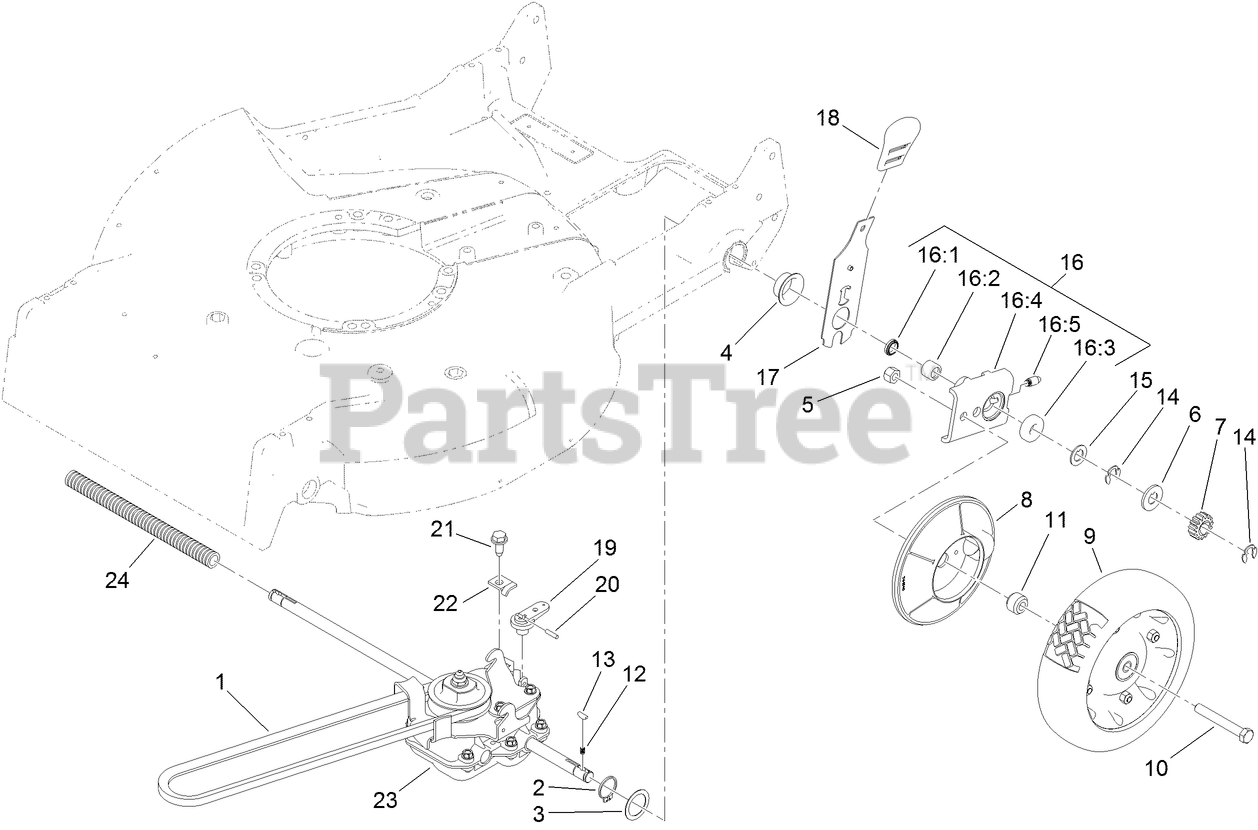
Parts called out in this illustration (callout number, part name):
1	V-BELT
2	RING-RETAINING
3	WASHER
4	CAP-END
5	NUT-LOCK, CONE
6	WASHER-THRUST, OUTER
7	GEAR-PINION
8	COVER-WHEEL
9	WHEEL AND TIRE ASM
10	SCREW-HH
11	SPACER-COVER, WHEEL
12	SPRING-COMPRESSION
14	RING-RETAINING
15	WASHER-THRUST, OUTER
16	PIVOT ARM ASM
16:1	SEAL-OIL
16:2	BEARING-CAGED NEEDLE ROLLER
16:3	BEARING-WHEEL
16:4	Arm-Pivot, Rear
17	REAR SPRING ARM ASM
18	KNOB-HOC
19	LEVER-SHIFT
20	PIN-SPRING
21	SCREW-HWHTF
22	CLAMP-CABLE
23	GEAR CASE ASM
24	COVER-SHAFT, DRIVE
